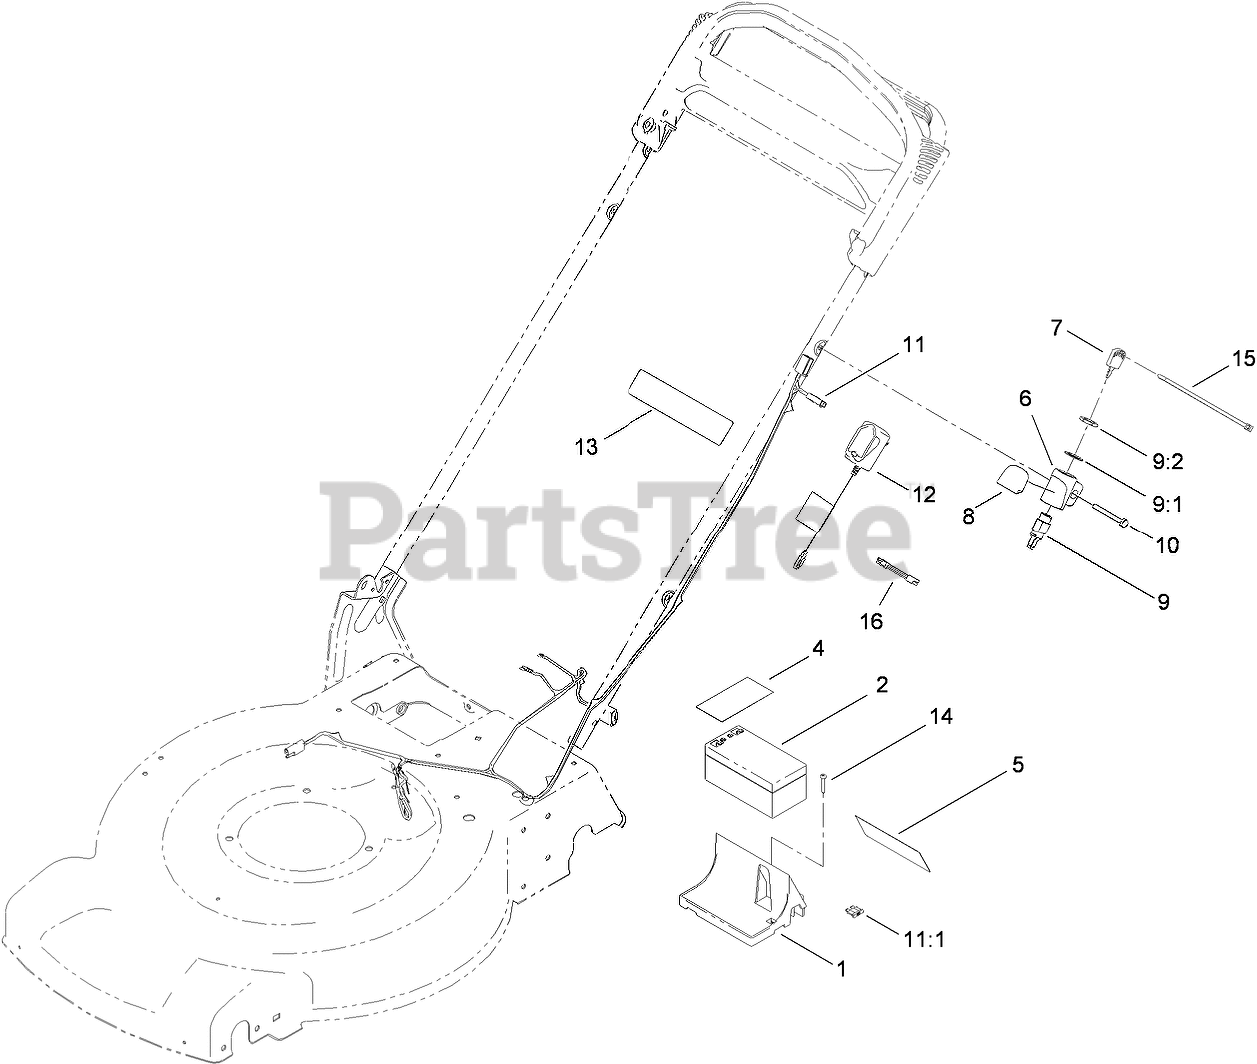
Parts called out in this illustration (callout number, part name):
1	TRAY-BATTERY
2	BATTERY-WET
4	DECAL-TERMINAL, BATTERY
5	DECAL-BATTERY TRAY
6	MOUNT-SWITCH
8	DECAL-ELECTRIC START
9	STARTER SWITCH ASM
9:1	WASHER-TOOTH, INTERNAL
9:2	NUT-HH
10	SCREW-HH
11	HARNESS-WIRE
11:1	FUSE-40 AMP
12	CHARGER-EUROPEAN, 12V DC
13	DECAL-WARNING
14	SCREW-PPH, PLASTITE
15	TIE-CABLE
16	ADAPTER-CHARGER
